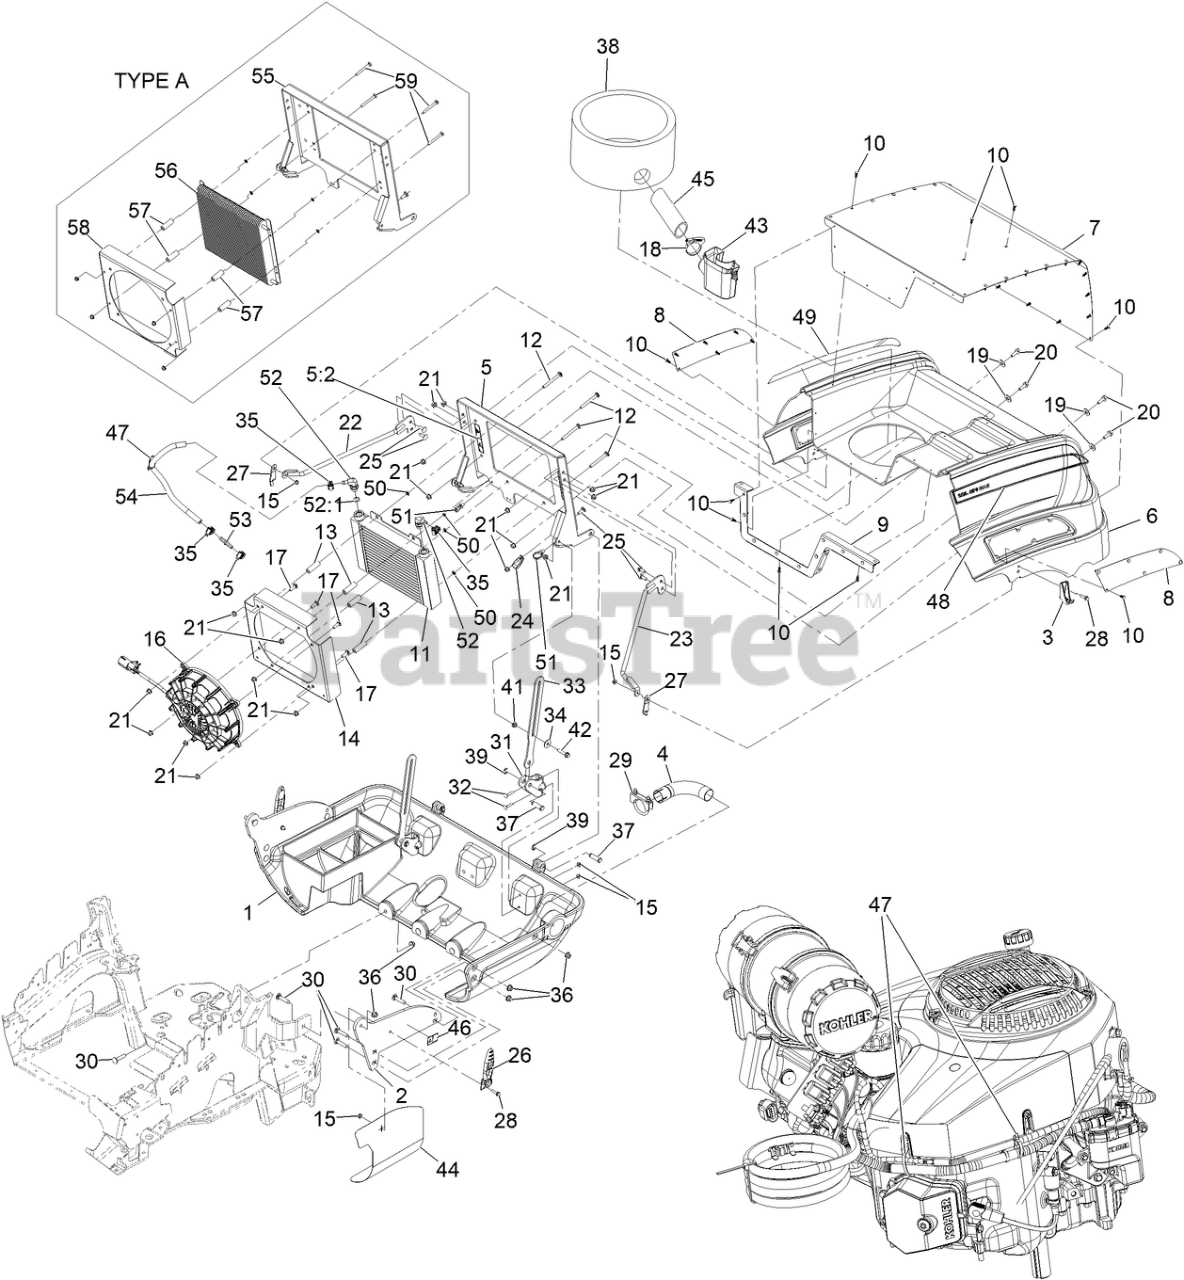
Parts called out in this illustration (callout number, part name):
1	Casting-Lower, Rear
2	Plate-Mount
3	LATCH-CATCH
4	Tube-Exhaust
5	Mount-Cooler
5:2	Decal-Warning
6	HOOD-EXMARK-GRAY
7	Screen-Intake
8	Screen-Intake
9	Cap-Perforation, Hood
10	Plug-Plastic
11	COOLER-OIL
12	SCREW-CARR
13	Tube-Spacer
14	Sheet-Fan Mount
17	SCREW-CARR
19	WASHER-FLAT
20	SCREW-HHF
21	NUT-HF, NI
22	Support-Hood, RH
23	Support-Hood, LH
25	BOLT-CARR
26	LATCH-RUBBER
27	Stop-Hood
28	SCREW-HHF
30	SCREW-CARR
31	Bracket-Mount, Slide
32	SCREW-CARR
33	Slide-Hood
34	WASHER-PLASTIC
35	Clamp-Hose
36	NUT-HF, NI
38	Foam-Inlet, Air
39	RING-RETAINING, EXTERNAL
42	SCREW-HHF
43	Mount-Hose
44	Barrier-Heat
45	Hose-Air Intake
46	DECAL-WARNING
47	TIE-CABLE
48	DECAL-LH STRIPE
49	DECAL-RH STRIPE
50	RING-RETAINING, BOLT
51	CLIP-TIE
52	FITTING-90
52:1	O-RING
53	Fitting-Mender-Strght
54	Hose-HYD, LP
55	Mount-Cooler
56	Cooler-Oil
58	Mount-Fan
59	SCREW-CARR
